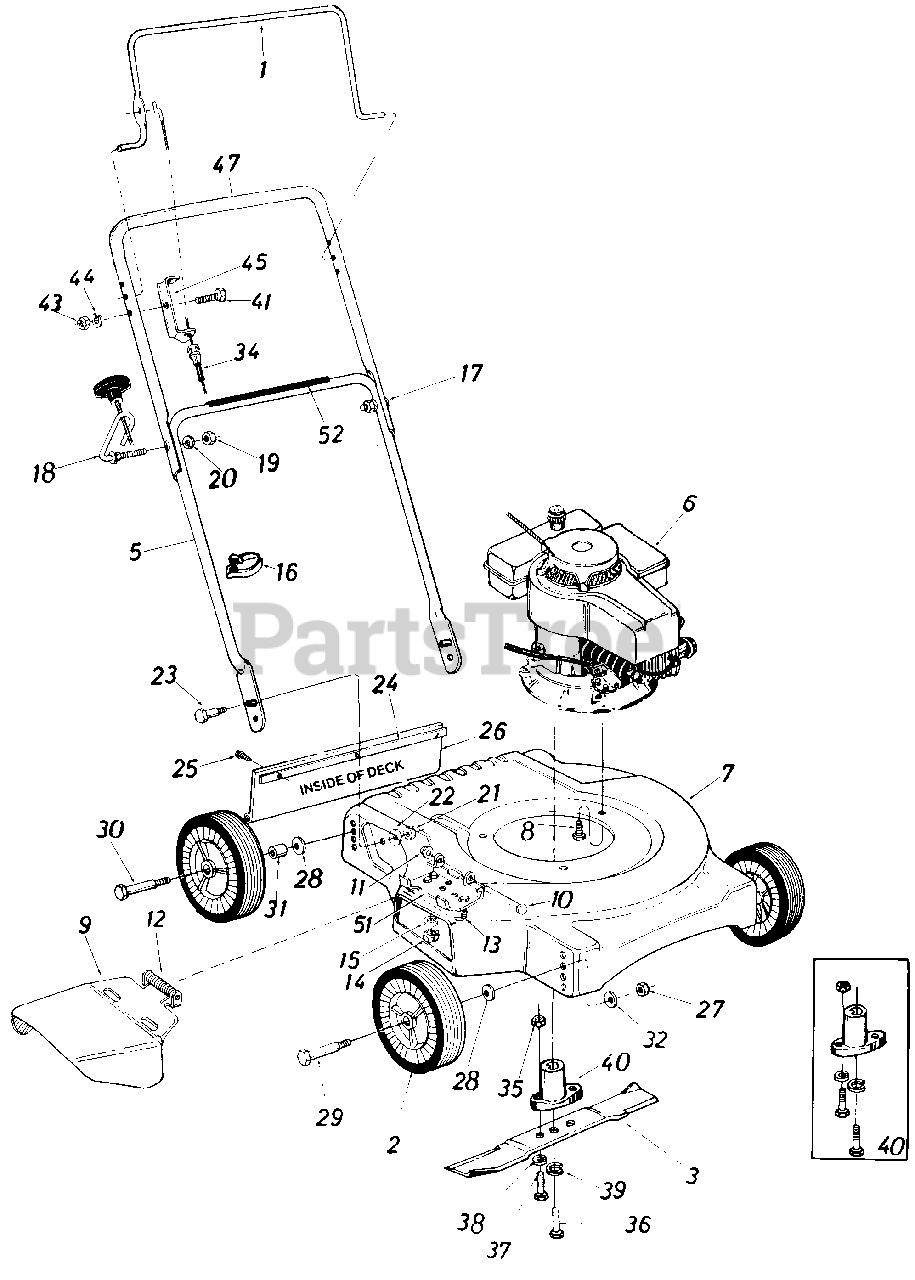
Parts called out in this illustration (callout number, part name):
1	Control Handle
2	Plastic Wheel Ass'y.
3	20" Blade
5	Lower Handle
6	Engine
9	Chute Deflector Ass'y.
10	Pivot Pin
11	Cap Speed Nut 1/4" Rod
12	Torsion Spring
13	Hex Bolt 1/4-20 x .50" Lg.
14	Hex Nut 1/4-20 Thd.
15	L-Wash. 1/4" I.D.
16	Cable Tie
17	Curved Carriage Bolt 5/16-18 x 1.38" Lg.
18	Rope Guide Bolt
19	Hex Nut 5/16-18 Thd.
20	L-Wash. 5/16" I.D.
21	Hex Ins. L-Nut 5/16-18 Thd.
22	Bell-Wash. .345" I.D. x .88" O.D.
23	Shld. Bolt .437" Dia. x .268" Lg.
24	Retainer Strip
25	Hex Wash. Hd. Self-Tap Scr. 1/4" x .62" Lg.
26	Rear Flap Ass'y.
27	Hex Nut 3/8-16 Thd.*
28	Bell-Wash. .400" I.D. x .88" O.D.
29	Shld. Bolt
30	Shld. Bolt
31	Spacer
32	Bell-Wash. .39" I.D. x 1.13" O.D.
34	Control Cable 43.0" Lg.
35	Hex Nut 5/16-24 Thd.*
36	Hex Bolt 3/8-24 x 1.00" Lg. Grade 5
37	Hex Bolt 5/16-24 x 1.00" Lg. Grade 5
38	L-Wash. 5/16" I.D.*
39	L-Wash. 3/8" l.D. Heavy Duty
40	Blade Adapter Kit
41	Hex Bolt 1/4-28 x 1.75" Lg.
43	Hex Nut 1/4-28 Thd.
44	L-Wash. 1/4" I.D.
45	Cable Mounting Brk't.
47	Upper Handle
51	Hinge Plate
52	Instruction Label Handle
